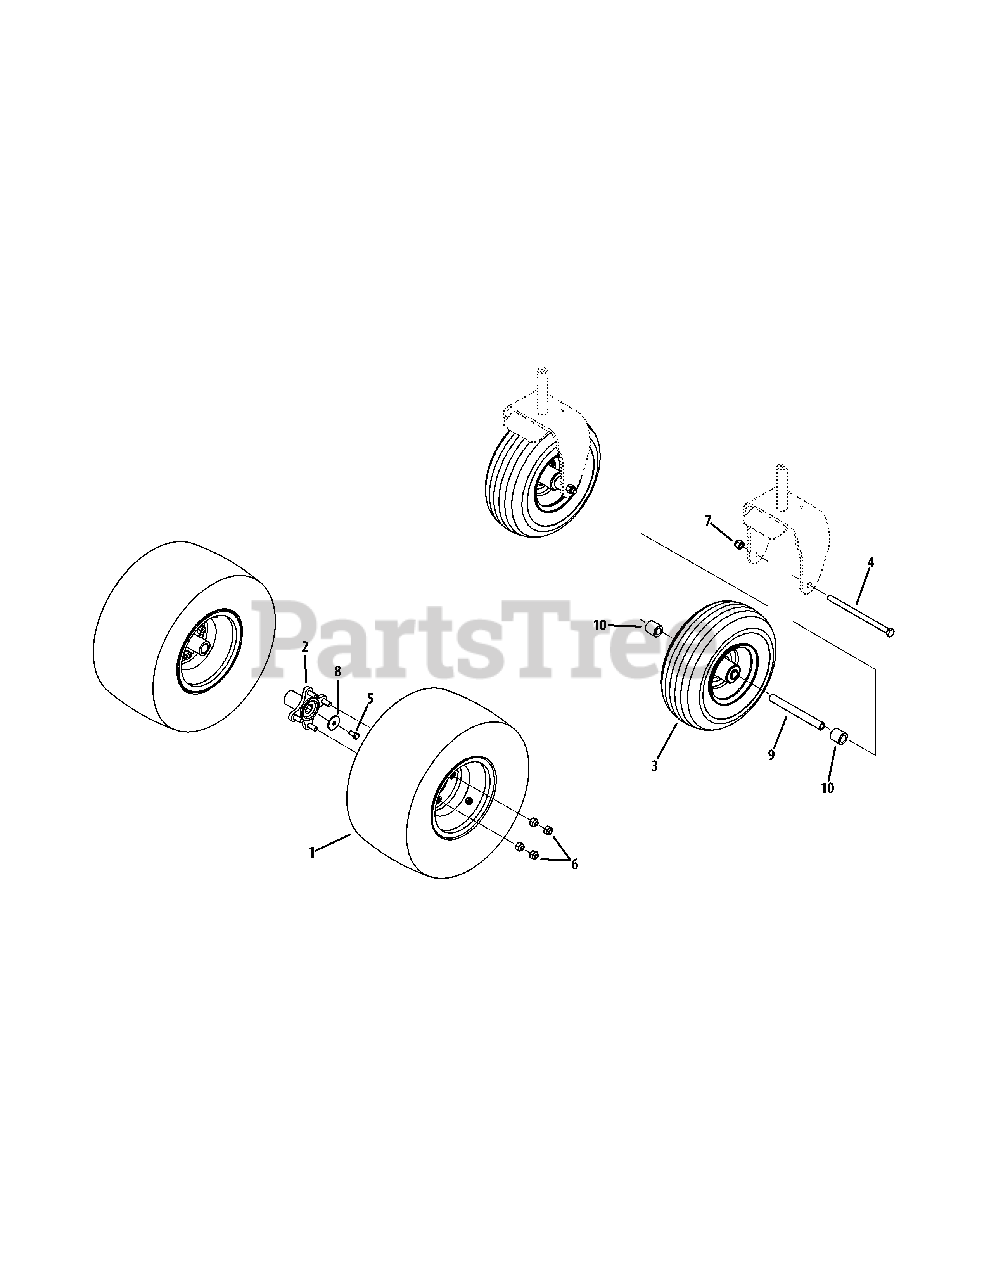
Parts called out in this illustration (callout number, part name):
1	Wheel Assy., 18 x 9.5-8
1	Wheel Assy., 20 x 10
2	Wheel Hub Assembly
4	Hex Screw, 1/2-13 x 8.5
5	Hex Screw, 3/8-16 x .750 (60" Only)
6	Lug Nut, 7/16-14
7	Hex Lock Nut, 1/2-13
8	Flat Washer, .390 x 1.500 x .134 (60" Only)
9	Spacer, .51 x .75 x 1.25
10	Hub, .76 x 1.23 x 1.25
